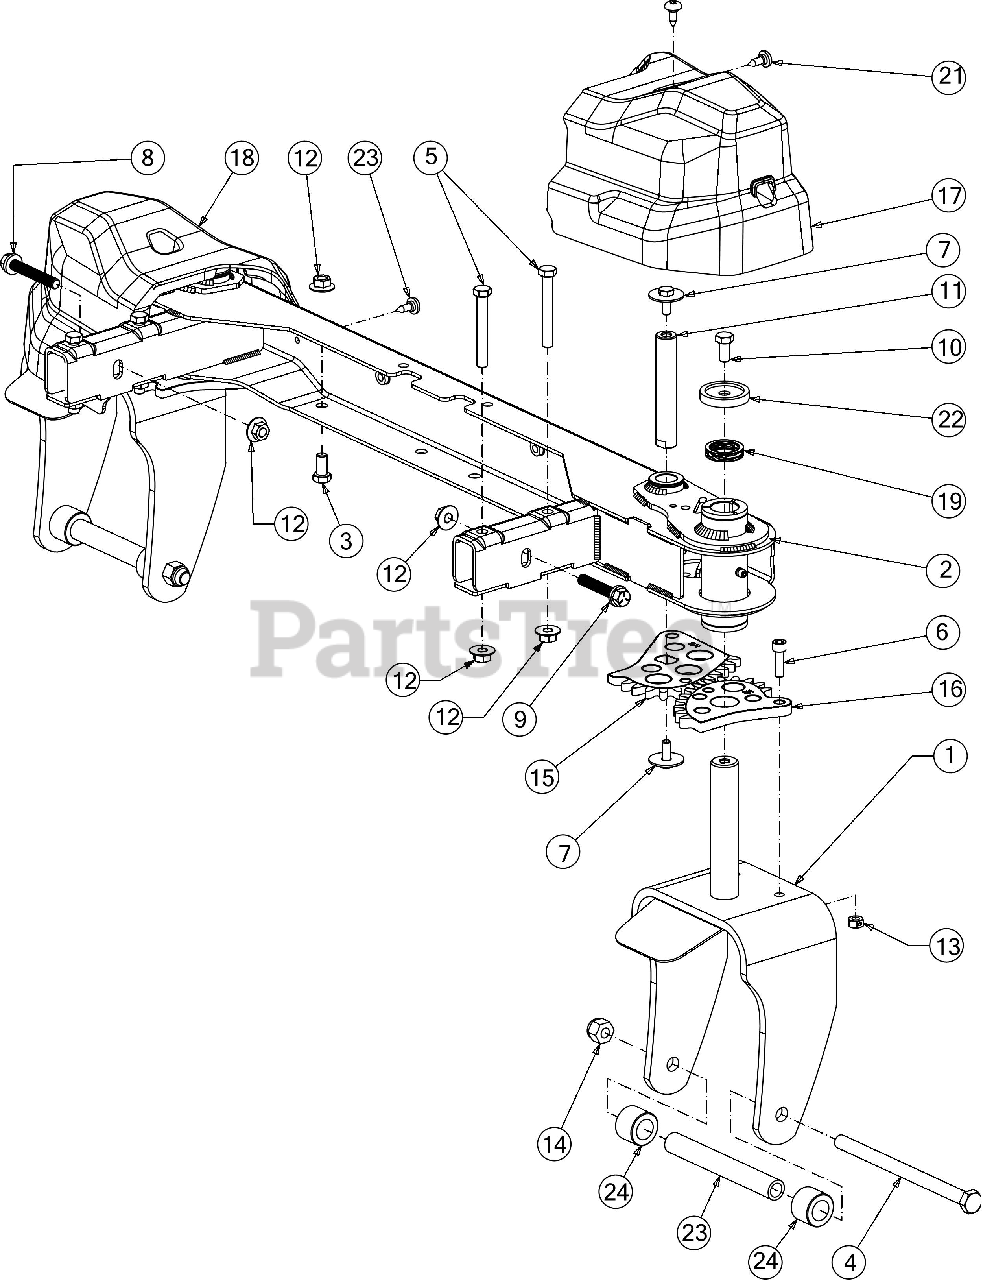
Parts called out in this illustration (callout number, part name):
1	CASTER WHEEL YOKE
2	FRONT AXLE ASSEMBLY
3	HEX SCREW 3/8-16 X .75
4	BOLT 1/2-20 X 7.25 GR5
5	SCREW 3/8-16 X 2.75 GR5
6	SCREW 5/16-18 X 1
7	SCREW 5/16-18 X.75 GR5
8	SCREW 3/8-16 X 2.25 GR5
9	SCREW 3/8-16 X 2.00 GR5
10	SCREW 3/8-16 X .75 GR 5
11	STEERING GEAR PIVOT SHAFT
12	FLANGE LOCK NUT
13	HEX NUT
14	HEX NUT CENTER
15	STEERING GEAR
16	STEERING SPUR GEAR 13T
17	AXLE COVER (RH)
18	AXLE COVER (LH)
19	WAVE WASHER
21	TORX SHOULDER SCREW 1/4-20
22	SHOULDER SPACER 1.75 OD
23	CASTER SPACER
24	HUB:76 X 1.23X.92 LG
